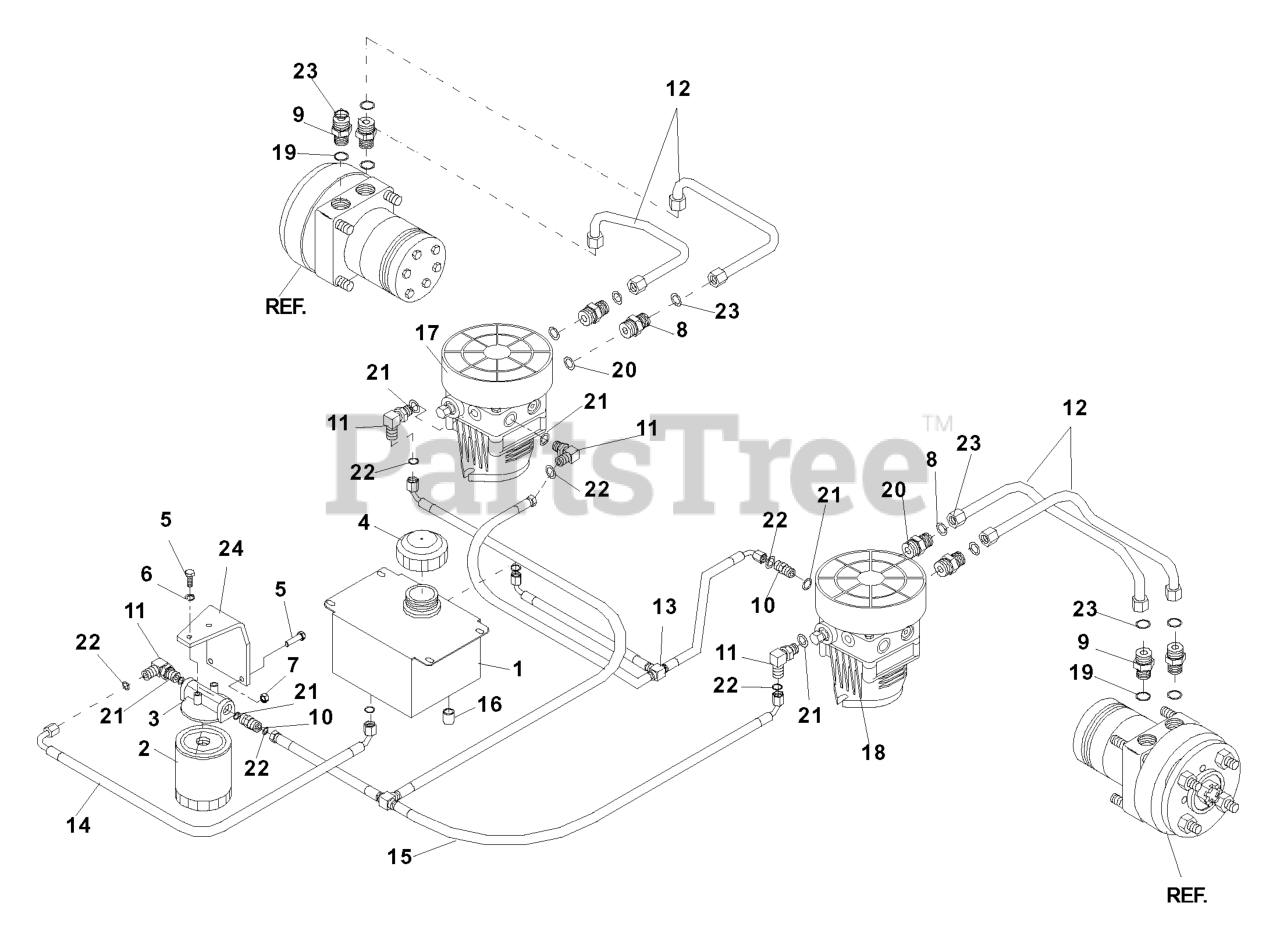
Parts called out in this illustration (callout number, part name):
2	HYDRAULIC OIL FILTER
3	FILTER HEAD
4	HYDRAULIC CAP
5	HCS 1/4C X 3/4 HCS
6	LOCKWASHER 1/4"
7	NUT.1/4-20.HEX.NYLOC.ZD
8	FITTING, STRAIGHT F6400-8-8-0
10	HYDRAULIC FITTING
11	ELBOW, F6801-6-6-0 90 DEGREE
12	RUBBER HYDRAULIC HOSE (1)
13	T-ASM, RETURN
16	NUT 9/16-18 JIC CAP
17	10CC PUMP W/6" FANS RH
18	10CC PUMP W/6" FANS LH
24	OIL FILTER BRKT
